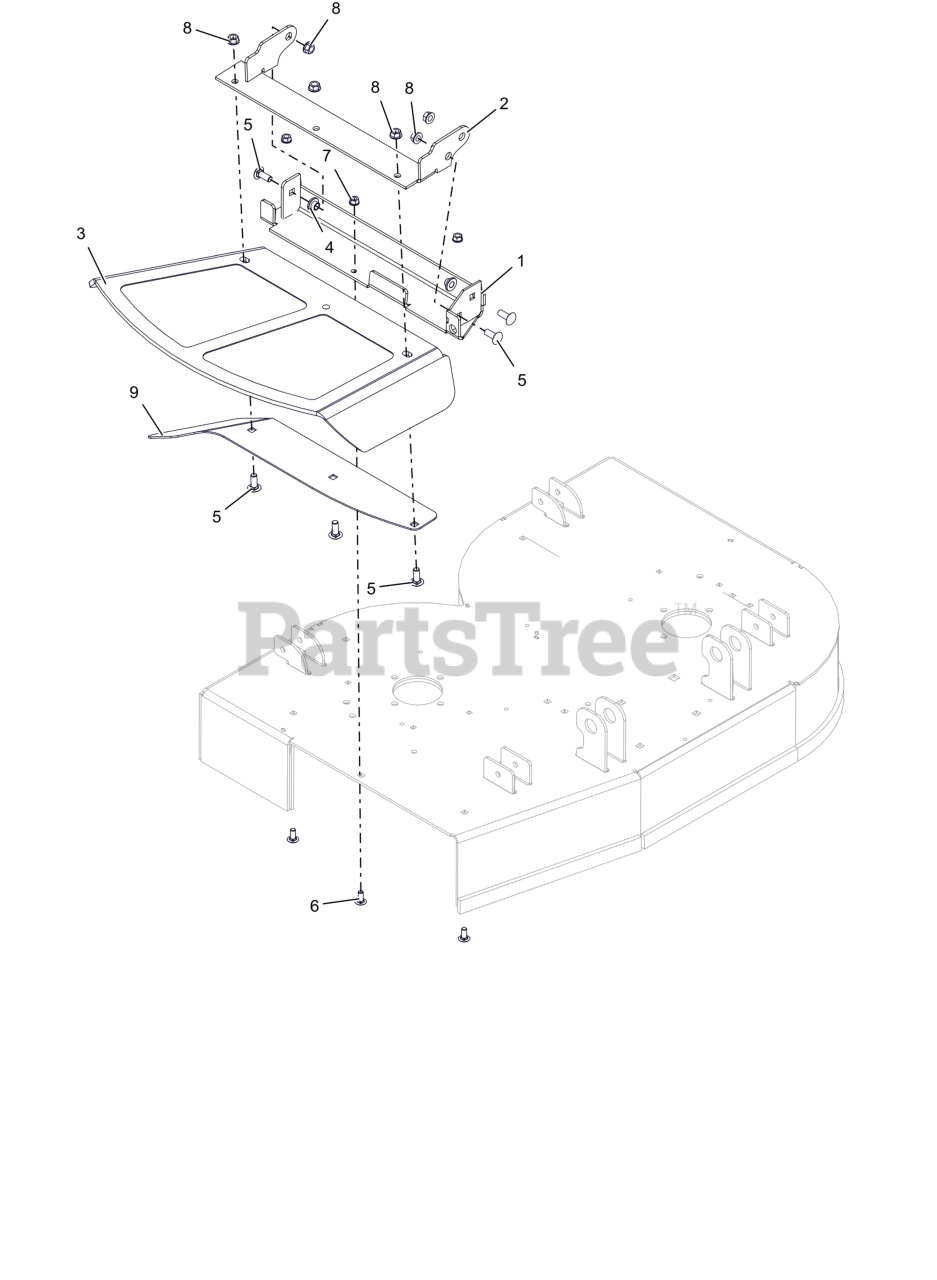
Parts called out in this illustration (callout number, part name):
1	WLDMT, DISCHARGE CHUTE (ORANGE)
2	WLDMT, CHUTE 36" MTG BRKT (ORANGE)
3	CHUTE,48-60" FRMD RUBBER DISCH
4	BSHG-FLG .385X.500X.875X.406
5	BLT,RHSSN .38-16X1.00 G5 ZCC
6	BLT, RHSSN.31-18X.750 G5 ZCC
7	NUT,LK-CTR-FLG .31-18 GF ZCC
8	NUT-LK-CTR-FLG .375-16 GF ZCC
9	PLATE, 32-36" DISCH CHUTE CLAMP (BLACK)
